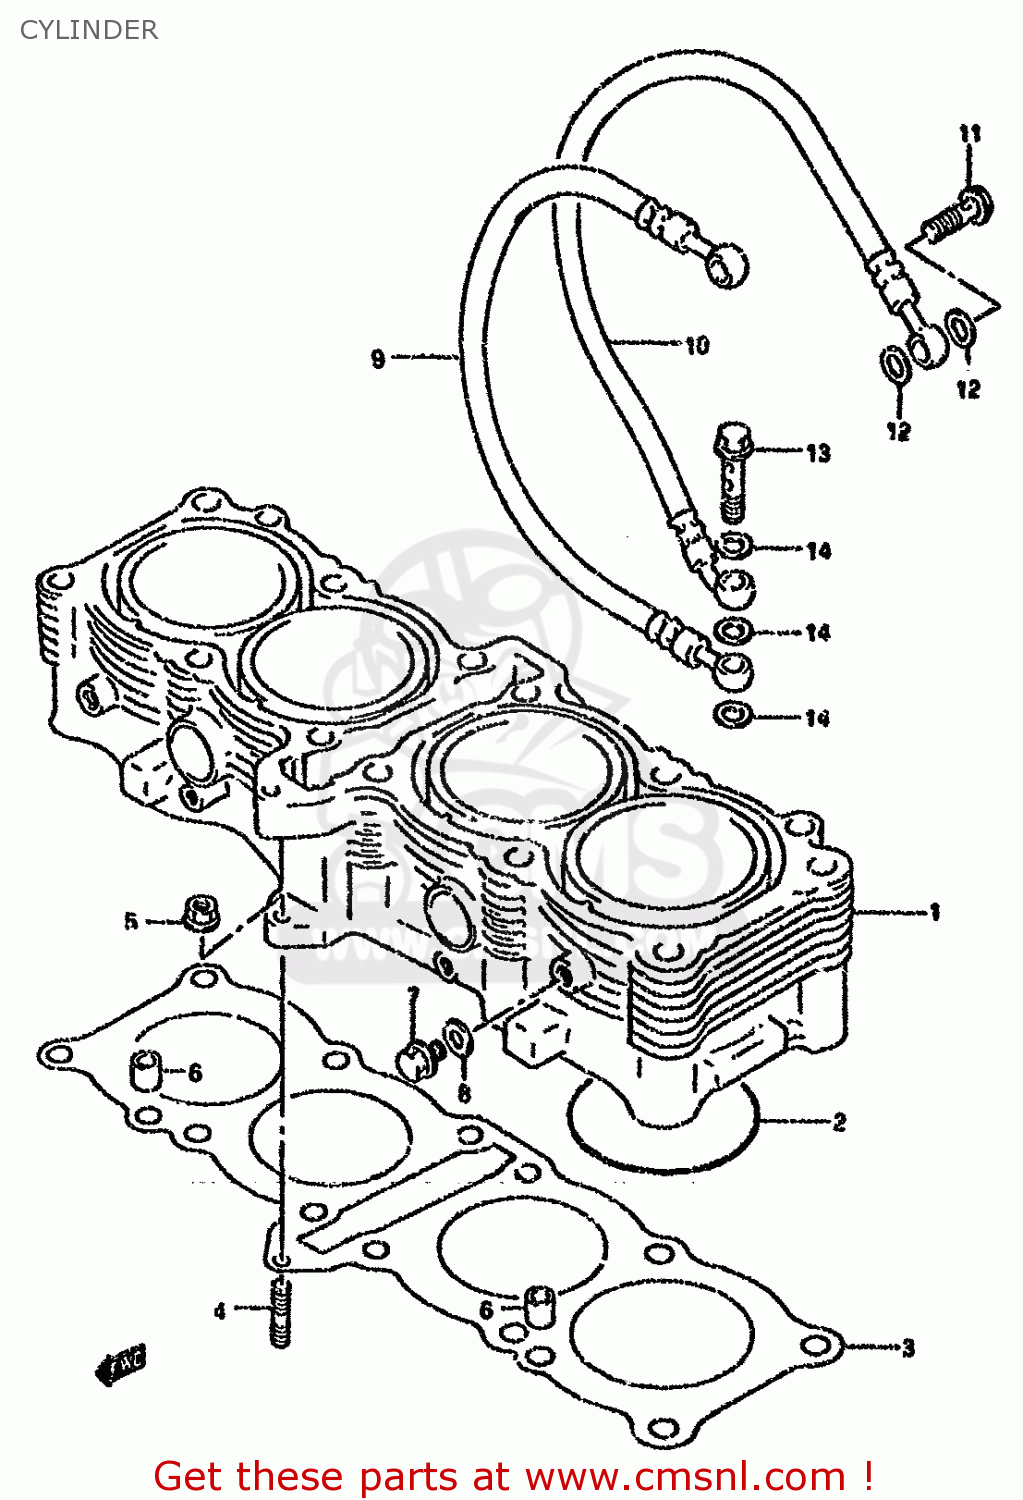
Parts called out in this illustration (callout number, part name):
1	CYLINDER COMP
2	O-RING
3	GASKET,CYLINDER
4	STUD,M6X1X32
5	NUT
6	PIN
7	BOLT,DRAIN
8	GASKET 8.2X14X1 (NAS)
9	HOSE,OIL
10	HOSE,OIL
11	BOLT,OIL PIPE UNION,NO
12	GASKET (NAS)
13	BOLT,OIL PIPE UNION,NO
14	WASHER(10X15X1.5)
